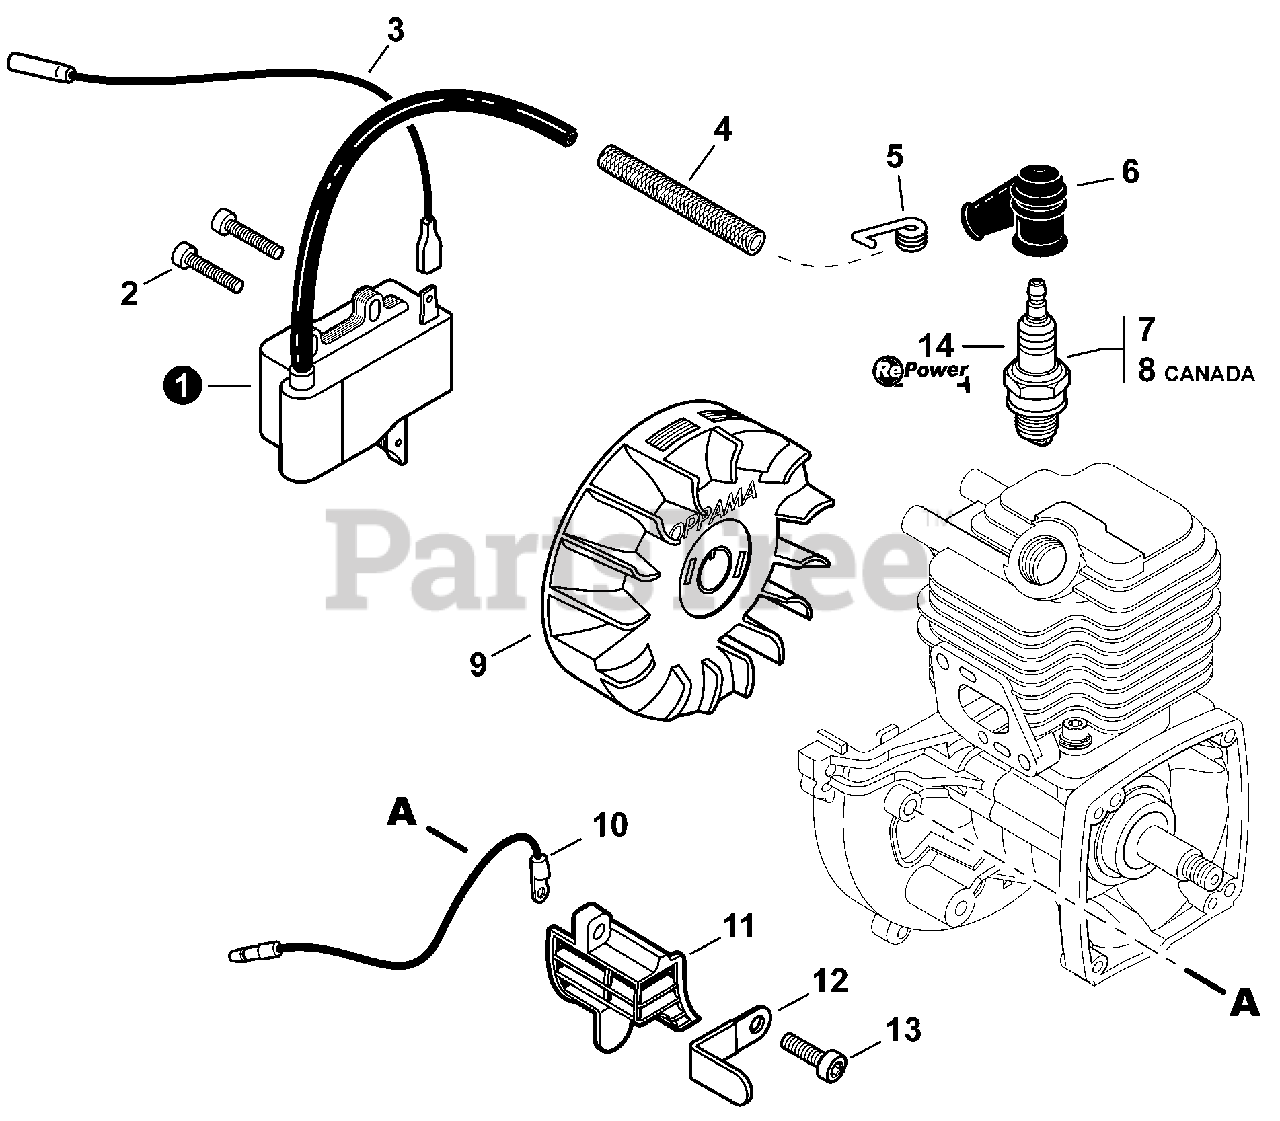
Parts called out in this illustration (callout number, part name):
1	COIL, IGNITION
2	SCREW - 4×20 -- TORX
3	LEAD - IGNITION
4	TUBE, INSULATOR
5	TERMINAL, SPARK PLUG CAP
6	CAP, SPARK PLUG
7	SPARK PLUG -- BPM8Y
8	SPARK PLUG -- BPMR8Y
9	FLYWHEEL
10	LEAD - GROUND
11	COVER, DEBRIS
13	SCREW - 5×16
14	TUNE-UP KIT - REPOWER
